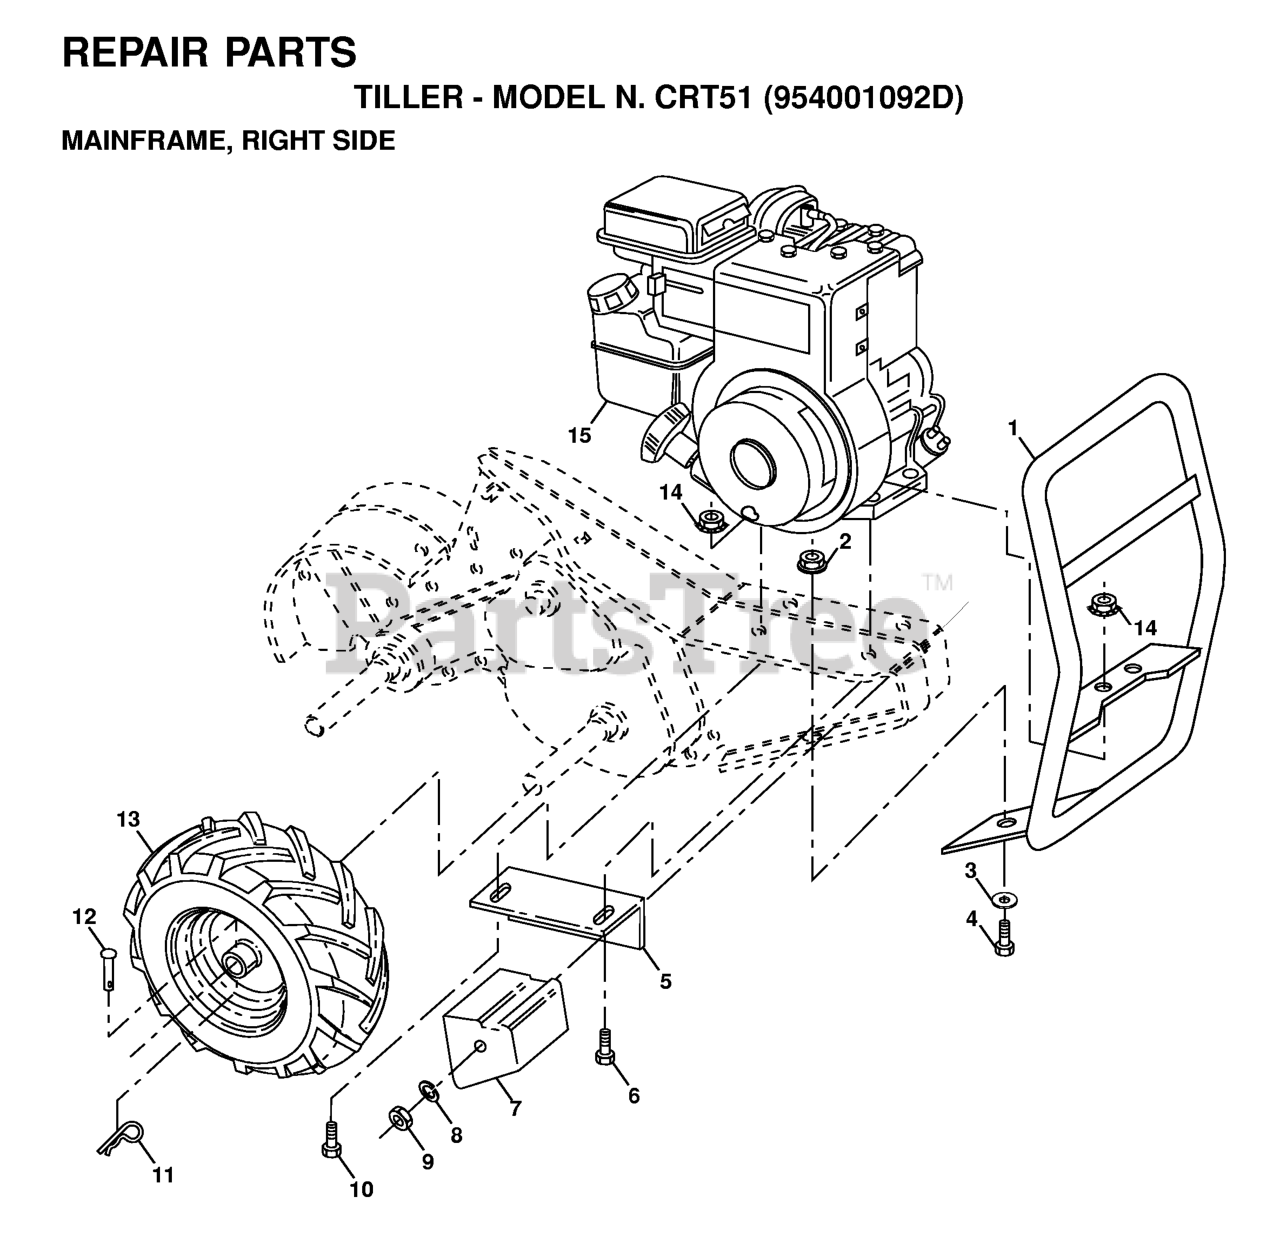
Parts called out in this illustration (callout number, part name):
1	BUMPER ASM TILLER
2	LOCKNUT-FLANGE 5/16-18
3	WASHER
4	BOLT
5	DNO BRACKET RH CRT
6	Bolt Fin Hex 5/16 - 18 Unc x 2 Gr. 2
7	COUNTERWEIGHT, RH
8	WASHER, LOCK 3/8
9	NUT.HEX.3/8-16UNC
10	BOLT
11	RETAINER M
12	RIVET,DRILLED
13	TIRE.16X4-8.CHEVRON.TILLER
14	NUT
532124366	RIM
532124718	VALVE STEM LT
